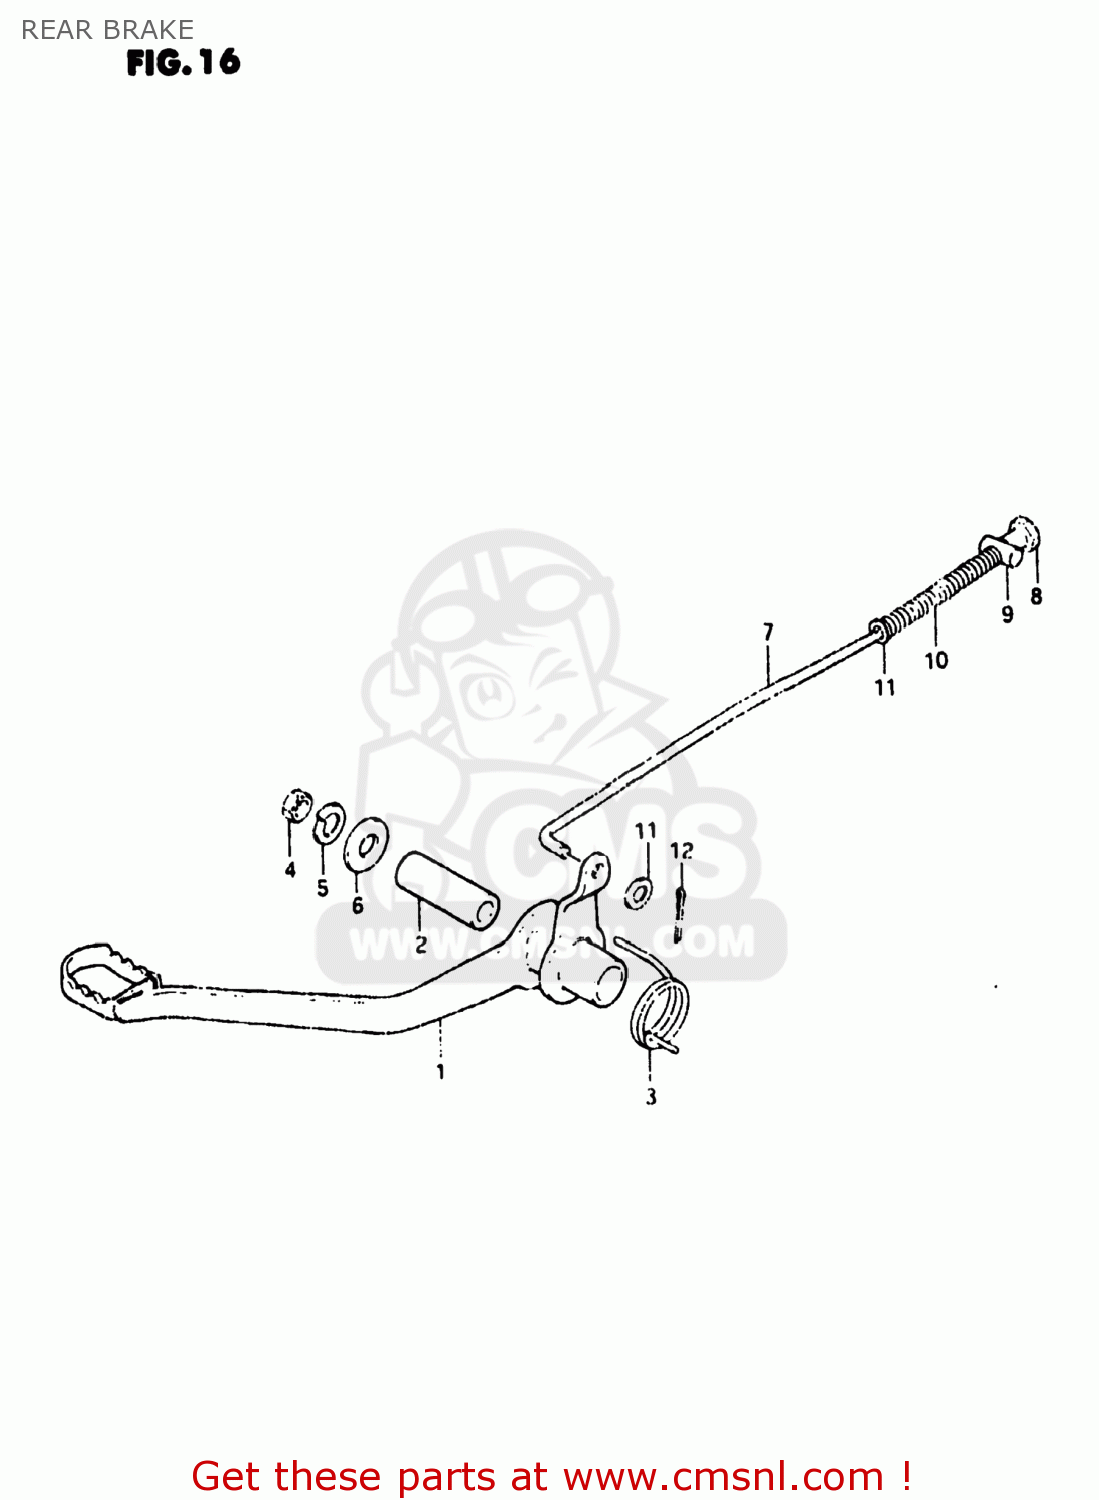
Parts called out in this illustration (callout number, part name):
1	PEDAL,BRAKE
2	SPACER,BRAKE PEDAL
3	SPRING,BRAKE PEDAL RETURN
4	NUT
5	LOCK WASHER
6	WASHER
7	ROD ASSY,RR BRAKE
8	NUT
9	PIN,10X19
10	SPRING
11	WASHER
12	PIN 20X20
